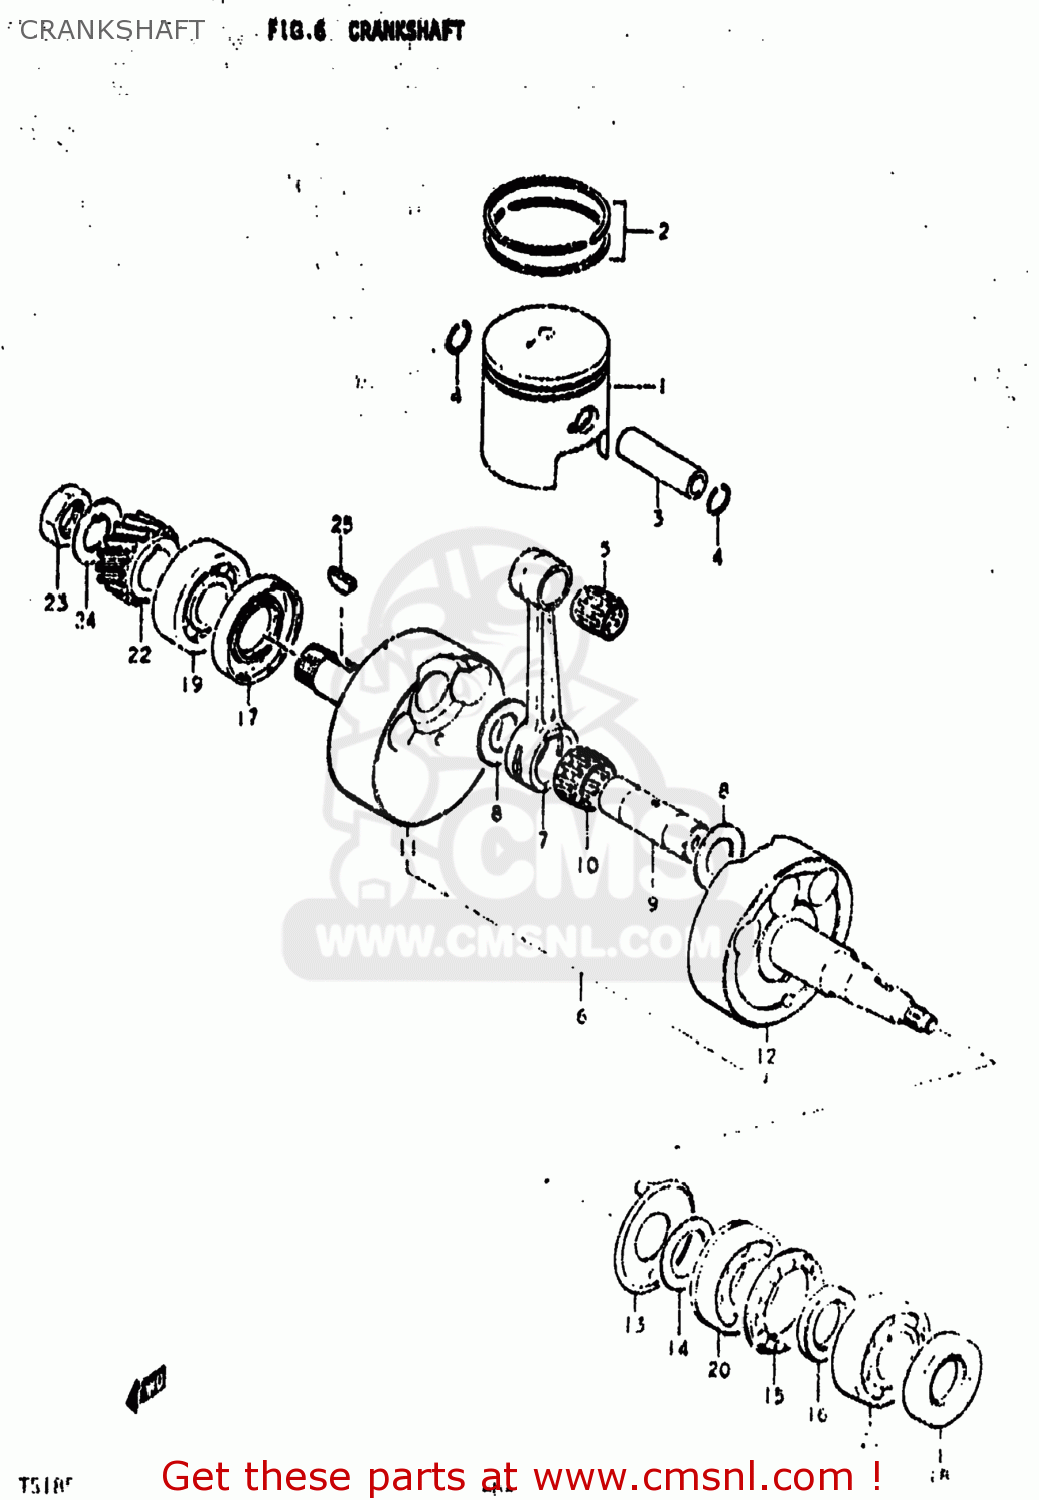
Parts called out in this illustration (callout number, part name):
1	PISTON
2	RING SET,PISTON
3	PIN,PISTON
4	RING,SNAP 16MM
5	BEARING
6	CRANKSHAFT ASSEMBLY
7	ROD, CONNECTING
8	WASHER(22X35X1)
9	PIN,CRANK
10	BEARING 22X28X16
11	CRANKSHAFT
12	CRANKSHAFT,LEFT
13	PLATE,CSHAFT OIL GUIDE
14	SHIM
15	SPACER,CRANKSHAFT,LEFT
16	SPACER
17	SEAL,OIL(26X52X8)
18	OIL SEAL
19	BEARING
20	BEARING
21	BEARING
22	GEAR,PRIMARY DRIVE
23	NUT
24	WASHER
25	KEY
